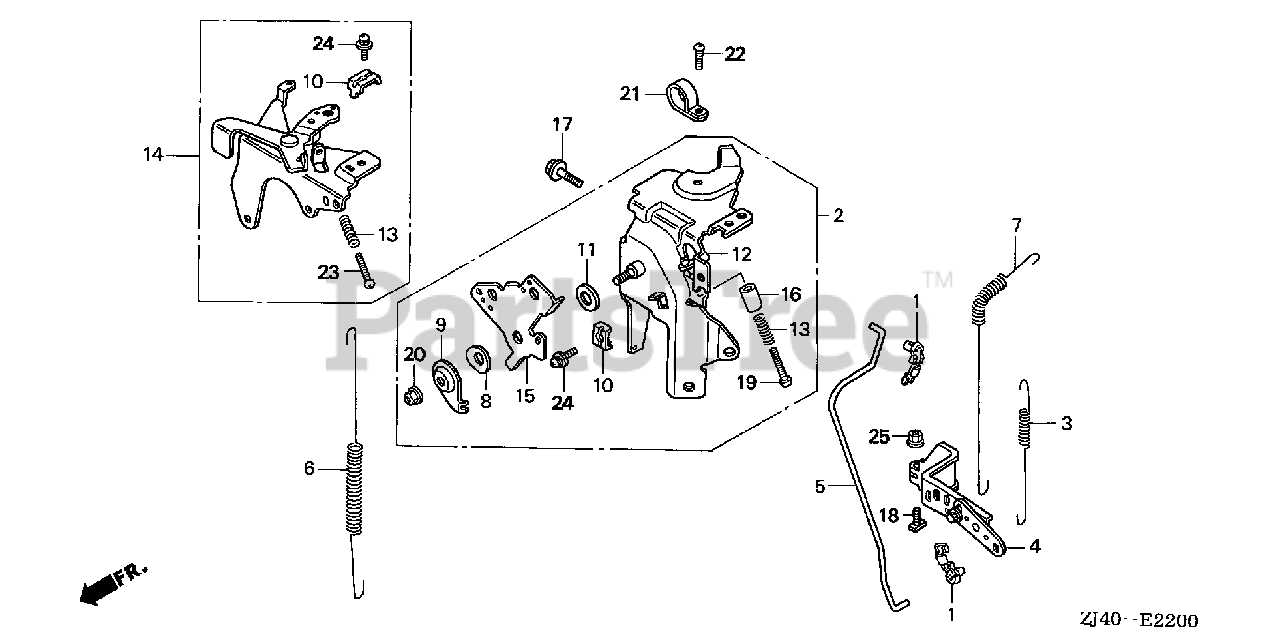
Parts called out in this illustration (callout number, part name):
1	JOINT, ROD
2	CONTROL ASSY. (REMOTE)
3	SPRING, STARTER
4	ARM, GOVERNOR
5	ROD, GOVERNOR
6	SPRING, GOVERNOR
7	SPRING, THROTTLE RETURN
8	SPRING, LEVER
9	WASHER, CONTROL LEVER
10	HOLDER, CABLE
11	SPACER, CONTROL LEVER
12	BASE, CONTROL
13	SPRING, CONTROL ADJUSTING
14	STAY ASSY., CHOKE CONTROL (REMOTE)
15	LEVER, WIRE
17	BOLT, FLANGE (6X12) (CT200)
18	BOLT, GOVERNOR ARM
19	SCREW, PAN (5X25)
20	NUT, SELF-LOCK (6MM)
21	CLAMP (D17.5)
22	SCREW, PAN (5X12)
23	SCREW, PAN (5X25)
24	SCREW-WASHER (5X16)
25	NUT, FLANGE (6MM)
